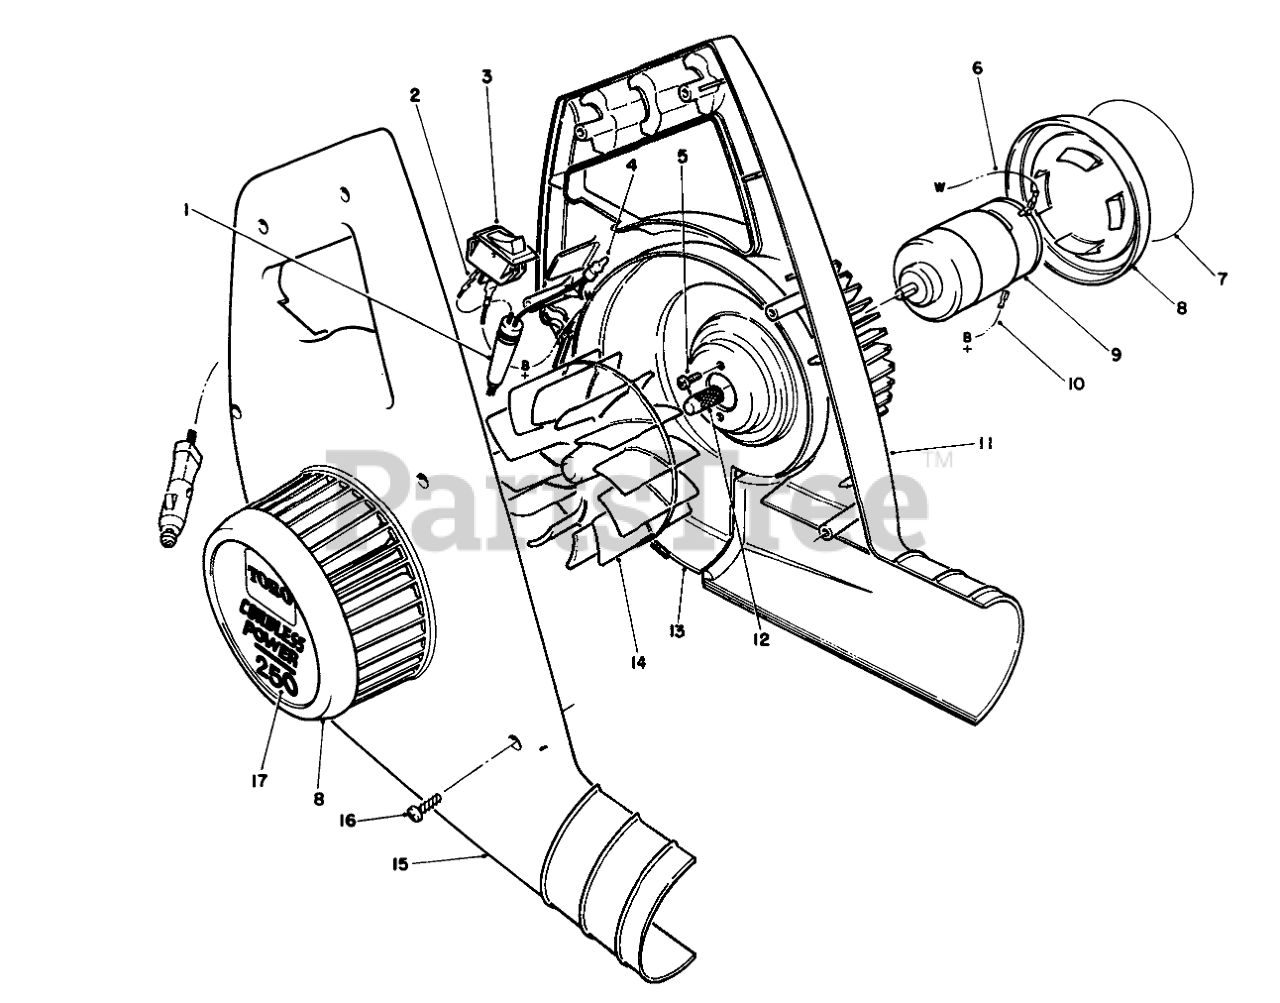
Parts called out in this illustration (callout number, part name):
1	POWER SUPPLY CORD
2	Terminal-Female
3	ROCKER SWITCH W/LETTERS
4	CONNECTOR WIRE JOINT
5	SCREW
6	WIRE ASSEMBLY
7	LABEL-SERIAL (250 CL)
8	MINI BV-INTAKE COVER
9	Motor (Incl. Ref. #5, & 12-14)
10	WIRE ASSEMBLY
11	Housing-L.H.
12	Shaft-Knurled
13	Cover-Motor
14	Impeller
15	HOUSING,RH,MINI-BLOWER
16	Screw
17	COVER LABEL(250 CORDLES
